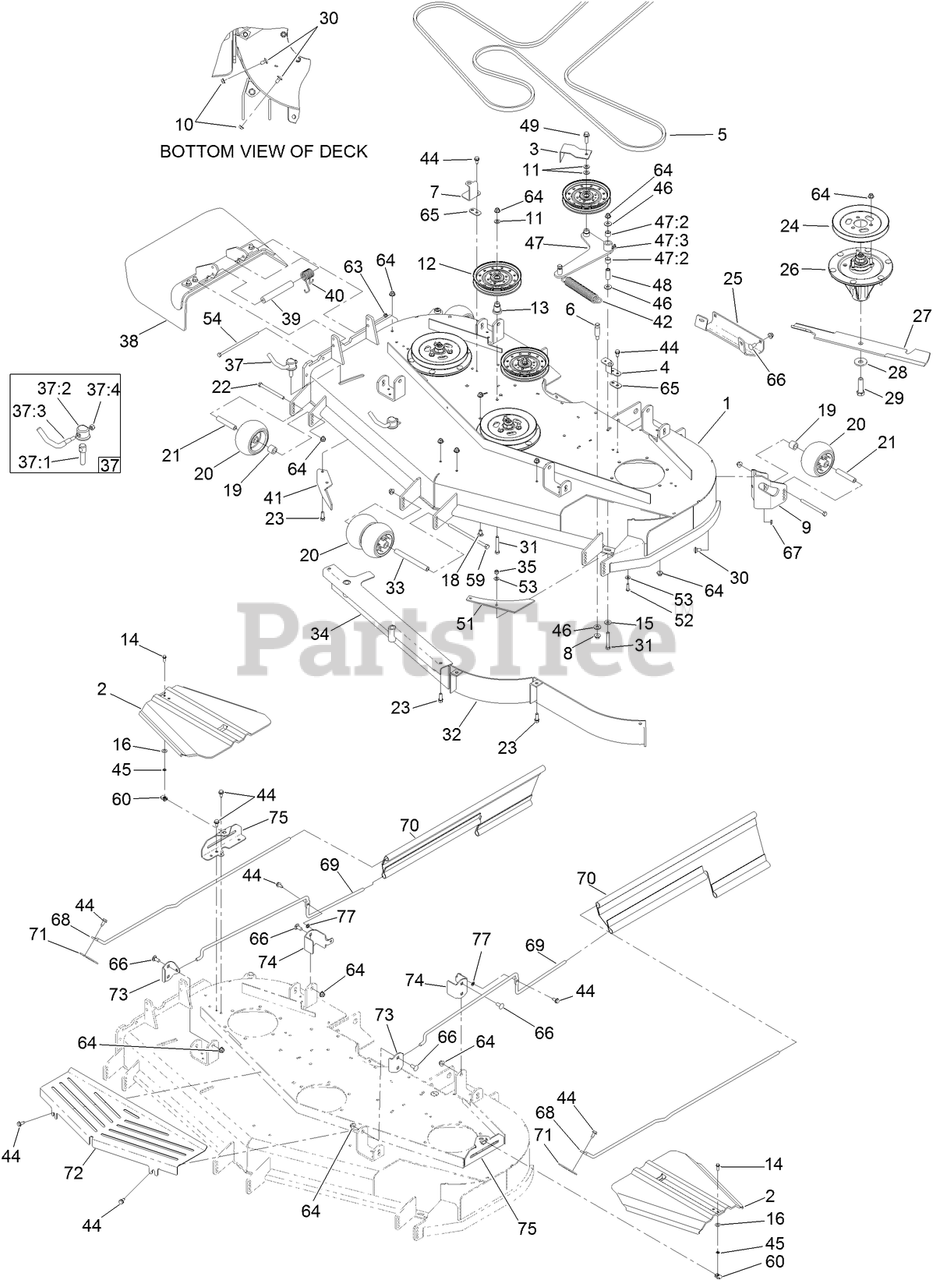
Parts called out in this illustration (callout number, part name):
1	DECK DECAL ASM
2	COVER-BELT
3	GUIDE-BELT
4	BRACKET-COVER, TALL
5	BELT-V
6	PIN-THREADED, SPRING ANCHOR
7	BRACKET-COVER
8	NUT-HF
9	MOUNT-WHEEL, LH
10	NUT-HHF, WHIZ
11	WASHER-FLAT
13	MOUNT-PULLEY
14	SCREW-HWH
15	WASHER-BELLEVILLE
16	WASHER-THRUST
18	SCREW-CARR
19	TUBE-SPACER
20	ROLLER-SCALP, ANTI
21	TUBE-SPANNER
22	SCREW-HH
24	PULLEY
25	PLATE-SKID
26	SPINDLE ASM
27	BLADE-HI FLOW
28	WASHER-BLADE BOLT, HEAVY
29	SCREW-BLADE
30	SCREW-HH
31	SCREW-HH
33	SPACER-WHEEL
35	NUT-LOCK, NI
37	LEVER ASM
37:1	SCREW-LOCK
37:2	CAP-LOCK
37:4	NUT-LOCK, NI
38	RUBBER DEFLECTOR ASM
39	SPACER
40	SPRING-TORSION
41	BAFFLE-DISCHARGE
42	SPRING-EXTENSION
44	SCREW-HWHTF
45	NUT-RETAINER
46	WASHER-FLAT
47	DECK IDLER ARM ASM
47:2	SLEEVE-BEARING
47:3	FITTING-GREASE, 90 DEG
48	BUSHING
49	SCREW-HHF
51	PLATE-TURBO
52	SCREW-HSBH
53	WASHER-SPRING
54	SCREW-HH
59	SCREW-HH
63	NUT-LOCK, NI
64	NUT-HF, NI
65	SPACER-BELT COVER
66	SCREW-CARR
68	ROD-SUPPORT, UPPER
69	ROD-SUPPORT, LOWER
70	GUARD-SIDE
71	BRACKET-MOUNTING, UPPER ROD
72	SHIELD-FRONT, DECK
73	BRACKET-MOUNTING, FRONT
74	BRACKET-MOUNTING, REAR
75	BRACKET-SUPPORT, SPINDLE COVER
77	NUT-PUSH
